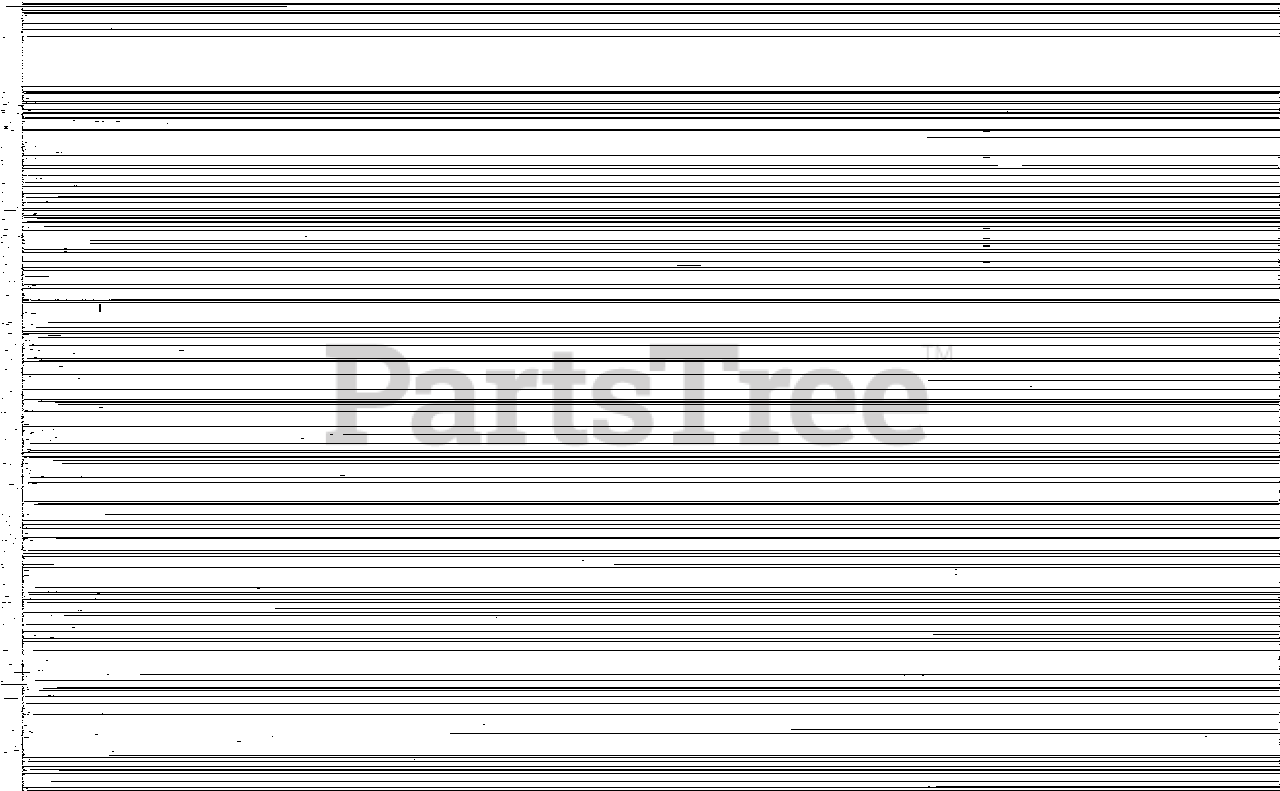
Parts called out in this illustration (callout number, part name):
1	TUBE, ELBOW
2	SCREW 5×14
4	TUBE, FLEXIBLE
5	CLAMP 77.8MM /101.6MM
6	CLAMP 58.7MM / 82.5MM
7	CLIP, CABLE
10	TUBE, BLOWER - STRAIGHT
11	TUBE, BLOWER - CURVED
13	TUBE, BLOWER - SWIVEL
14	SCREW, TAPPING
15	STRAP, TIE
16	BRACKET, HANDLE - RIGHT
17	BRACKET, HANDLE - LEFT
18	KNOB, SCREW M6×50MM
19	NUT, FLANGE 6
21	SCREW 5×20
22	BRACKET, THROTTLE
